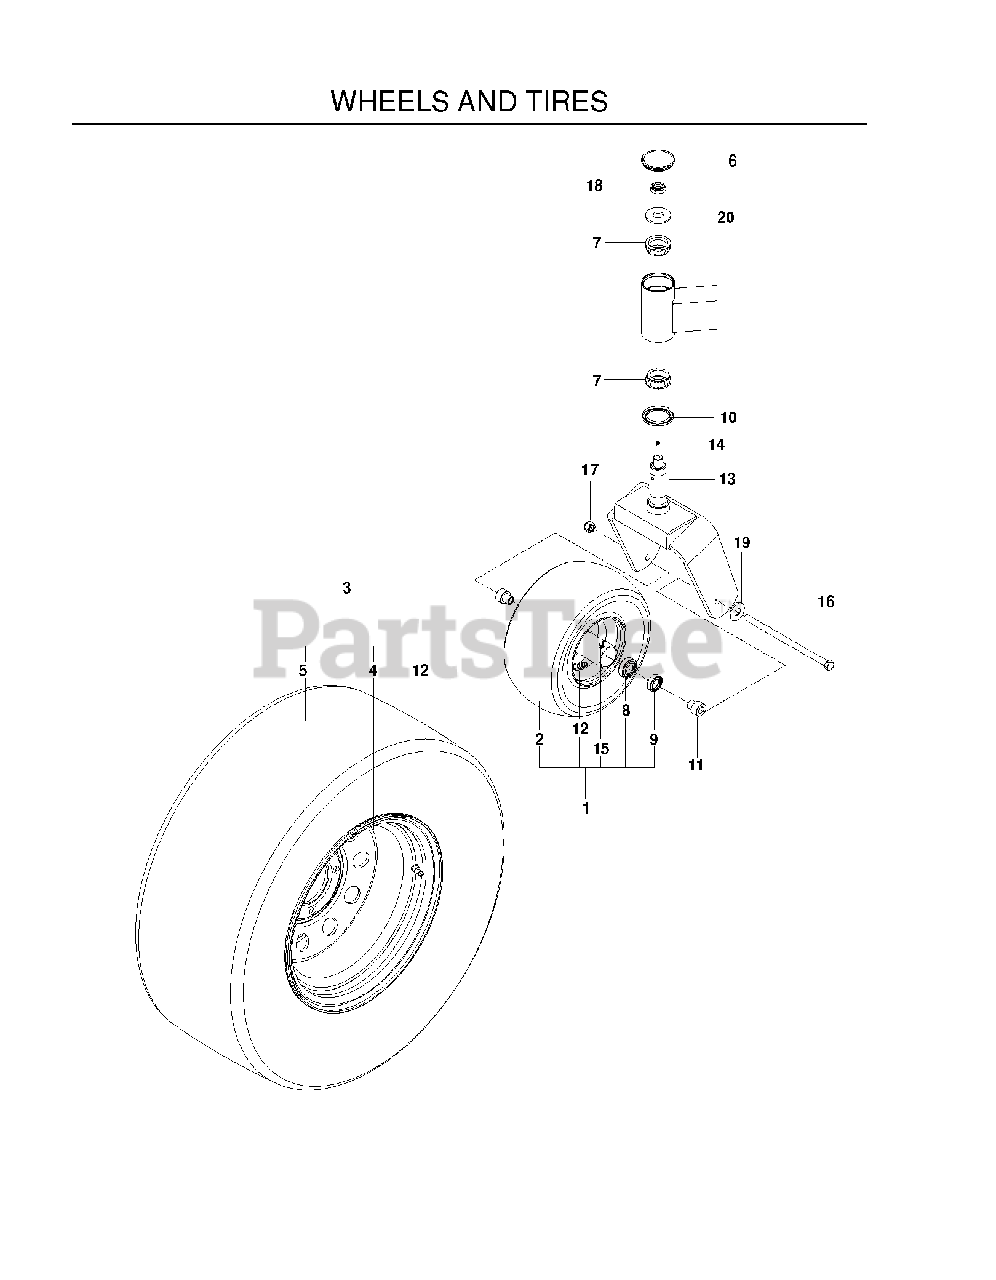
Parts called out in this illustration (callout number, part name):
1	FRONT TIRE ASSY
2	TIRE - SMOOTH
3	TIRE ASSY 24-12
4	RIM 2.5" NEG OFFSET 8.5" WIDE
5	REAR TIRE 24X12 TURFMASTER
6	CAP, DUST
7	BEARING, TAPPER ROLLER
8	TAPERED BEARING W/RACE
10	SEAL, BEARING
11	AXLE SPACER
12	VALVE STEM TR-412
15	ZERK
16	HEX SCREW 1/2-13 X 9.5 GR5
17	NUT, 1/2-13 HEX FLG NYLOC ZD
18	NUT, 3/4-16 HEX THIN NYLOC ZD
19	WASHER 1/2" FLAT
20	WASHER, 3/4 HARDENED
